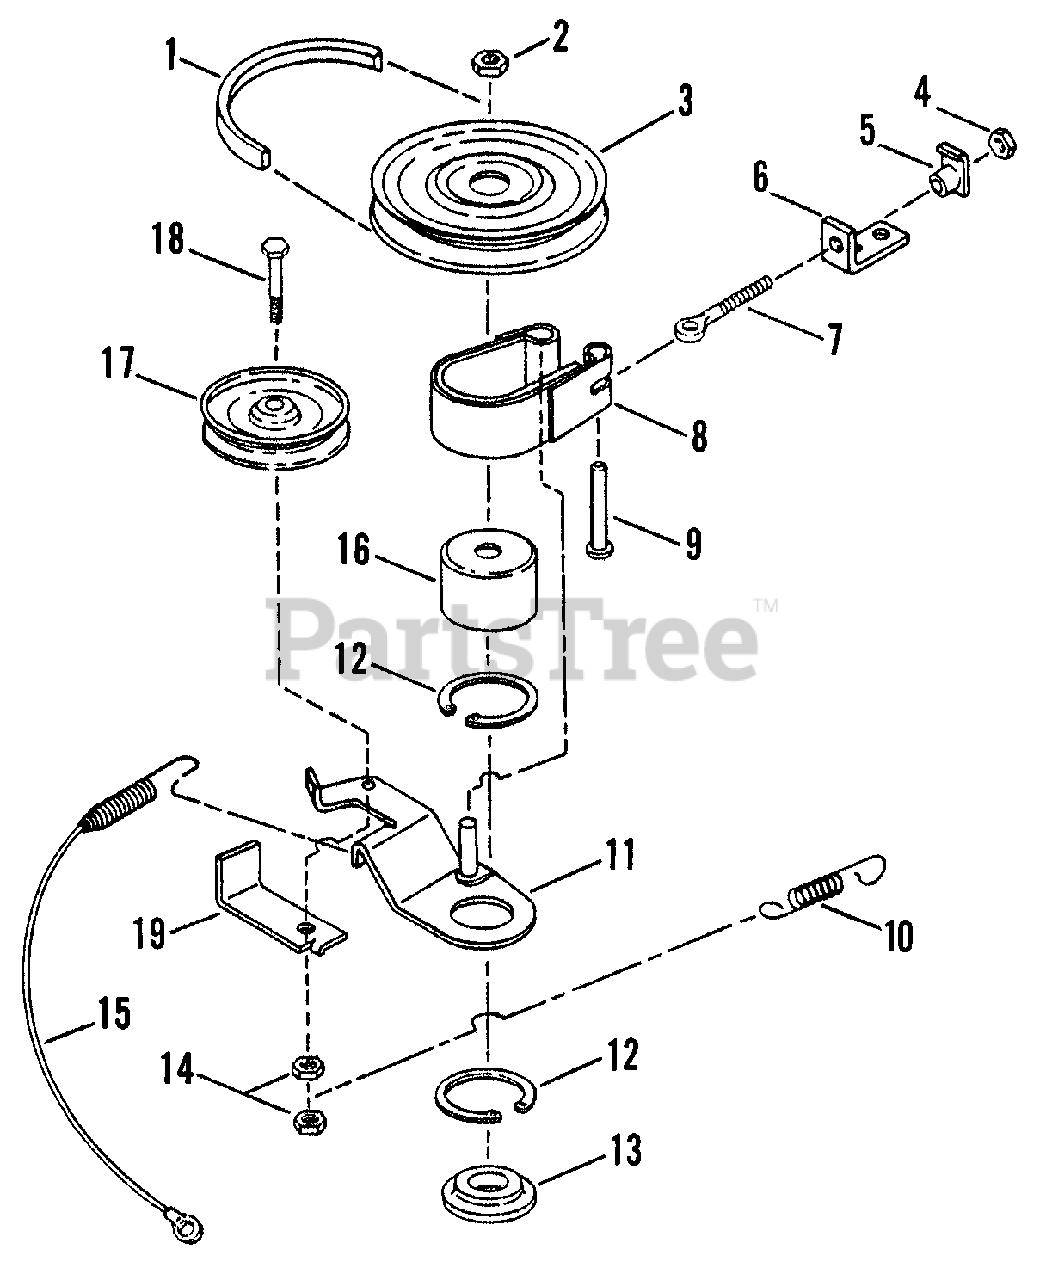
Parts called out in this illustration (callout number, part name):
1	BELT, Drive 103.1" EL
1	BELT, Drive 101.7" EL
2	NUT, 3/4-16 Hex Jam
3	PULLEY, Drive
4	NUT, 1/4-20 Hex
5	TEE-NUT, 1/4-20
6	ANCHOR, Brake
7	BOLT, 1/4-20 Eye
8	ASSEMBLY, Brake Band
9	PIN, Clevis, 1/4 x 1 1/4"
10	SPRING, Blade Brake
11	ASSEMBLY, Brake Arm
12	RING, 2" External Retaining
13	WASHER, Spindle
14	NUT, 3/8-24 Hex Lock
15	CABLE, Blade 19.75"
16	DRUM, Brake
17	PULLEY, Idler
18	SCREW, 3/8-24 x 2" Hex Head Cap
19	GUIDE, Belt
